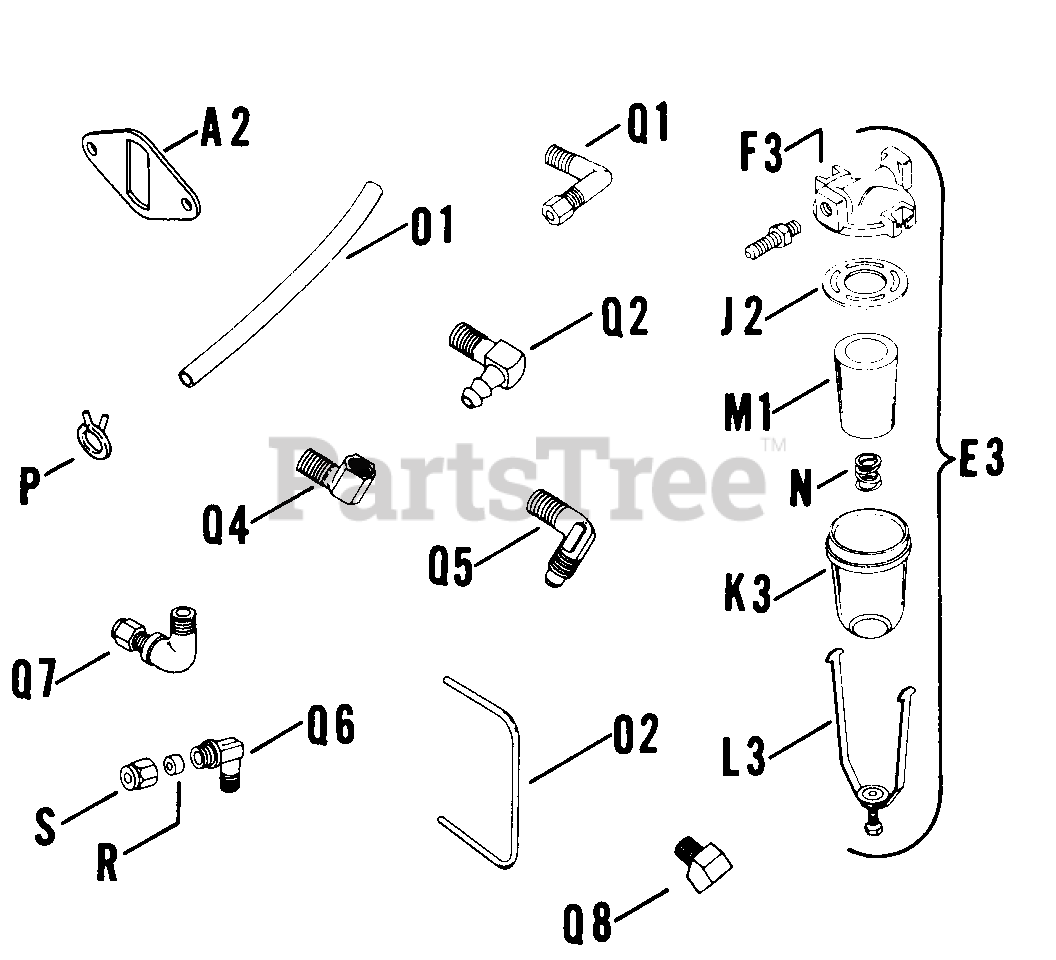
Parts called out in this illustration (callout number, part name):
O1	LINE - USE X-697-4
P	CLAMP HOSE USE X-426-9
Q1	Elbow, compression 90ø
R	SLEEVE
S	NUT - (#DSC)
